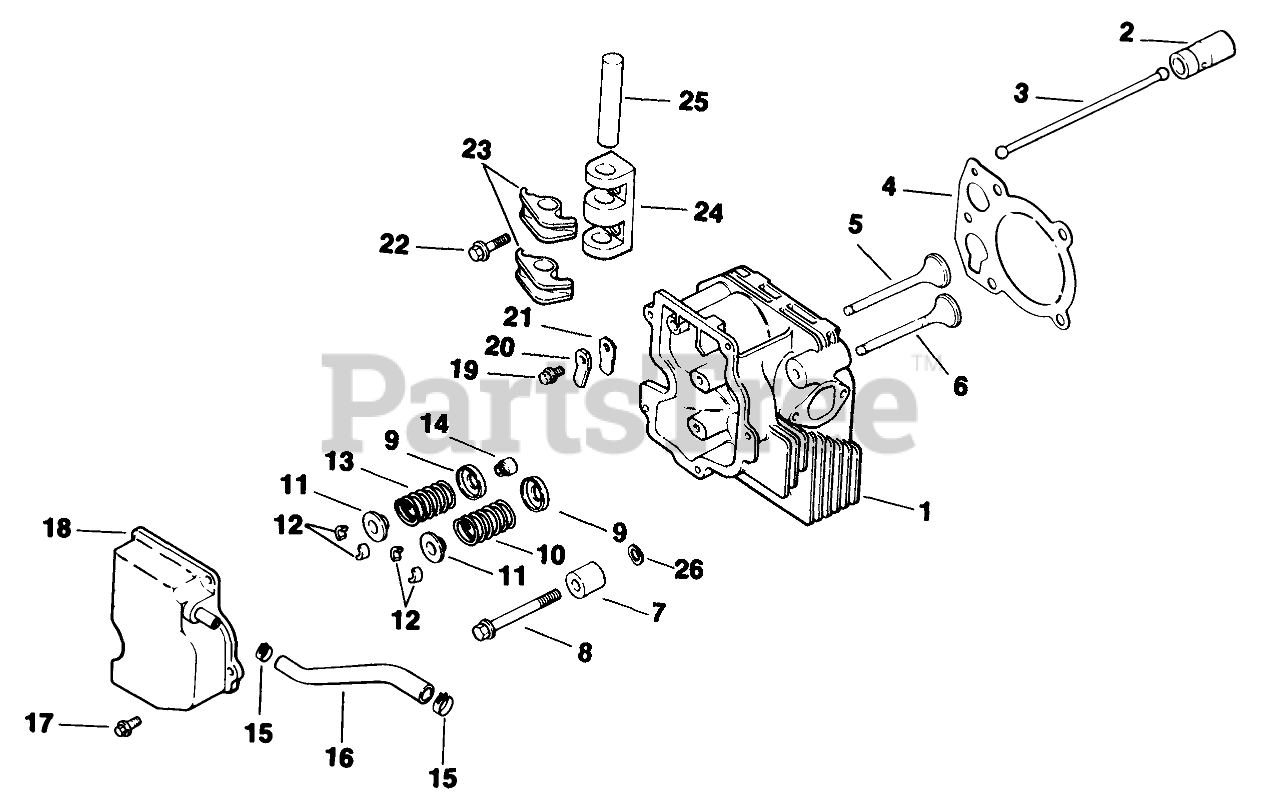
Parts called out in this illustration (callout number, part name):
1	Cylinder Head
2	Lifter-Valve
3	Rod-Push
4	Gasket-Cylinder Head
5	Valve-Intake STD
6	Valve-Exhaust STD
7	Spacer
8	Screw
9	Retainer-Spring
10	Pulley
11	Cap-Valve Spring
12	Kit-Retainer
13	Spring-Valve Intake
14	Seal
15	Clamp
16	Hose-Breather
17	Screw
18	Cover-Valve
20	Retainer-Reed
22	Screw
23	Arm-Rocker
24	Bridge-Rocker Arm
25	Shaft-Rocker Arm
26	Washer
